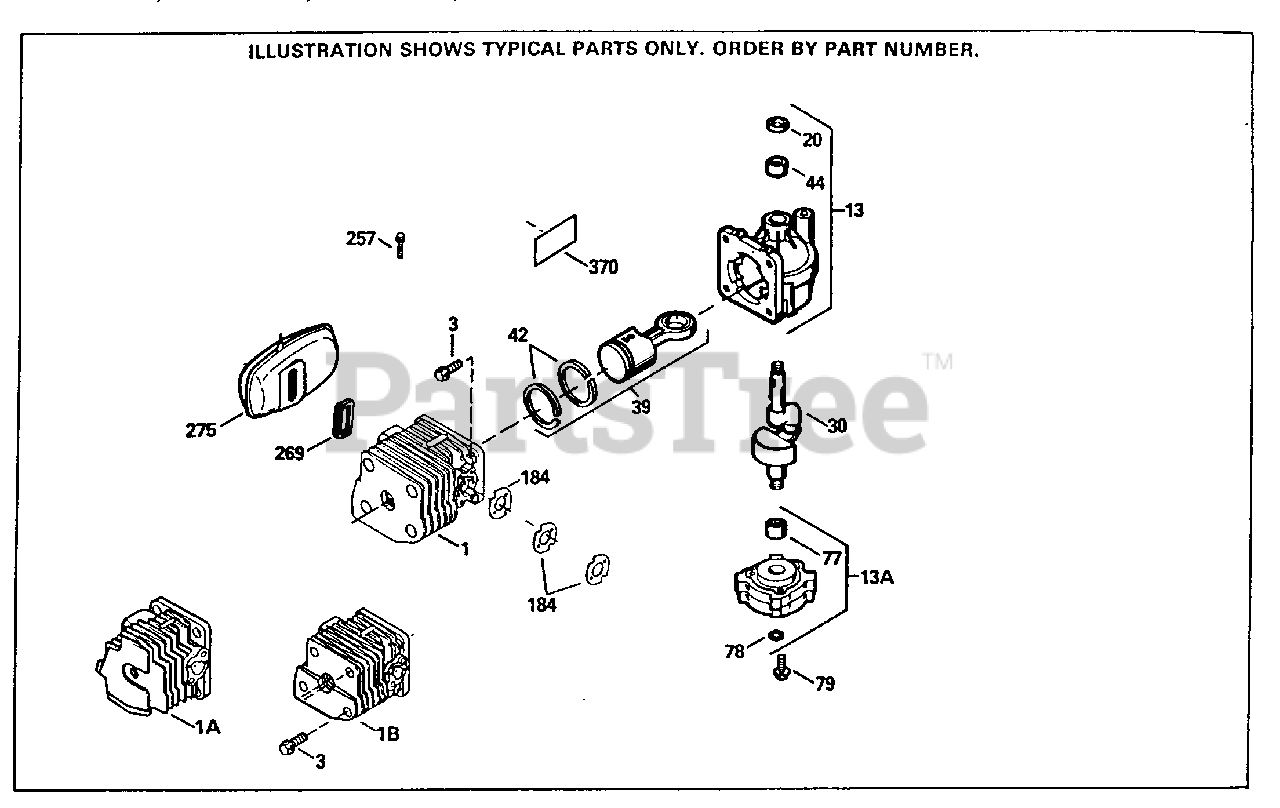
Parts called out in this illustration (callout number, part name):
1A	"Cylinder
3	Screw, Torx 1/4-20 x 43/64"
13	Crankcase Assy. (Incl. 20 & 44)
13A	Cover Assy., Crankcase Incl. 77 & 78
20	Seal, Oil
30	Crankshaft
39	Piston & Rod Assy. (Incl. 42)
42	Ring Set, Piston
44	Bearing, Cartridge
77	Bearing, Cartridge
78	Seal, Oil
79	Screw, 1/4-20 x 3/4"
184	Gasket, Adapter
269	Gasket, Exhaust
370	Decal, Instruction
